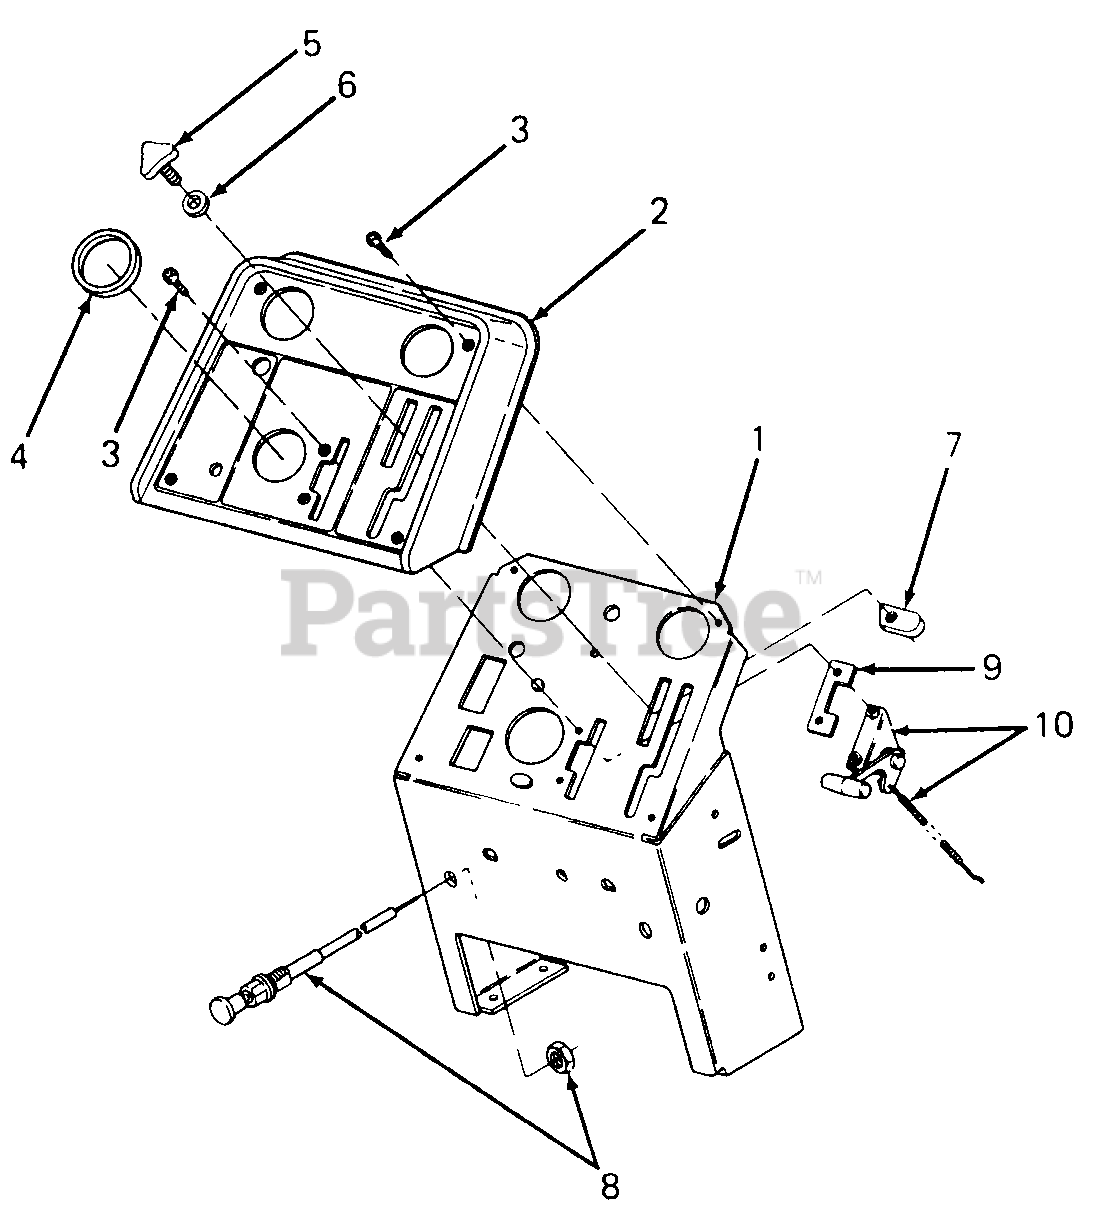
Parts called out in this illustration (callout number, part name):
2	Panel, Instrument
3	Screw, Pan Hd Cutting, #10-24 X .75 Lg
4	Grommet, Instrument Panel
6	Washer, Flat, .266 X .625 X .035 Thk
7	Stop, Detent Handle
8	Choke Cable w/Nut
9	Plate, Throttle Closure
10	Control, Throttle
